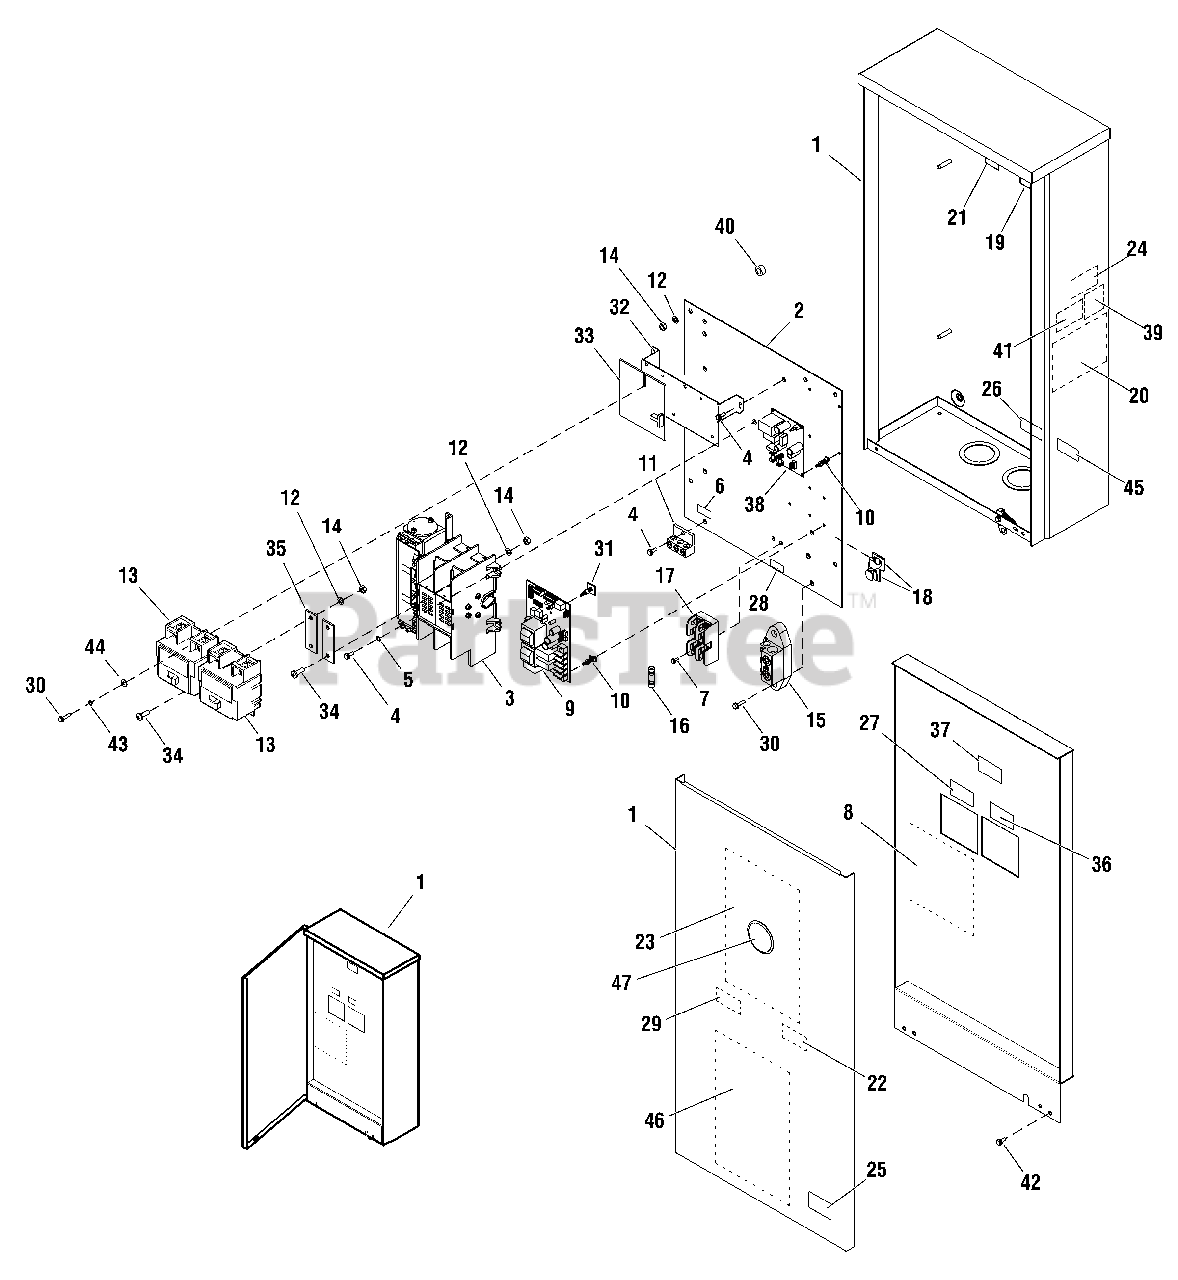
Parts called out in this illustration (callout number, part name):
1	ENCLOSURE
2	BACK PANEL
3	SWITCH, Transfer
4	* TRILOBULAR, #10-32 x 1/2
5	* WASHER, External Tooth, #10
6	DECAL
7	* SCREW, Hex Head, Trilobular, #6-32 x 3/8
9	BOARD, Circuit
11	LUG
12	* WASHER, Lock, 1/4
13	BREAKER, Circuit, 200A
14	* NUT, 1/4-20
28	DECAL
30	* SCREW, Hex Head, Trilobular, #10-32 x 3/4
34	* SCREW, Phillips Head, 1/4-20x 3/4
35	BAR, Bus
37	DECAL
39	DECAL
40	SPACER
41	DECAL
42	* TRILOBULAR, #10-32 x 3/8
43	* WASHER, Lock, #10
44	* WASHER, Flat, #10
45	DECAL
